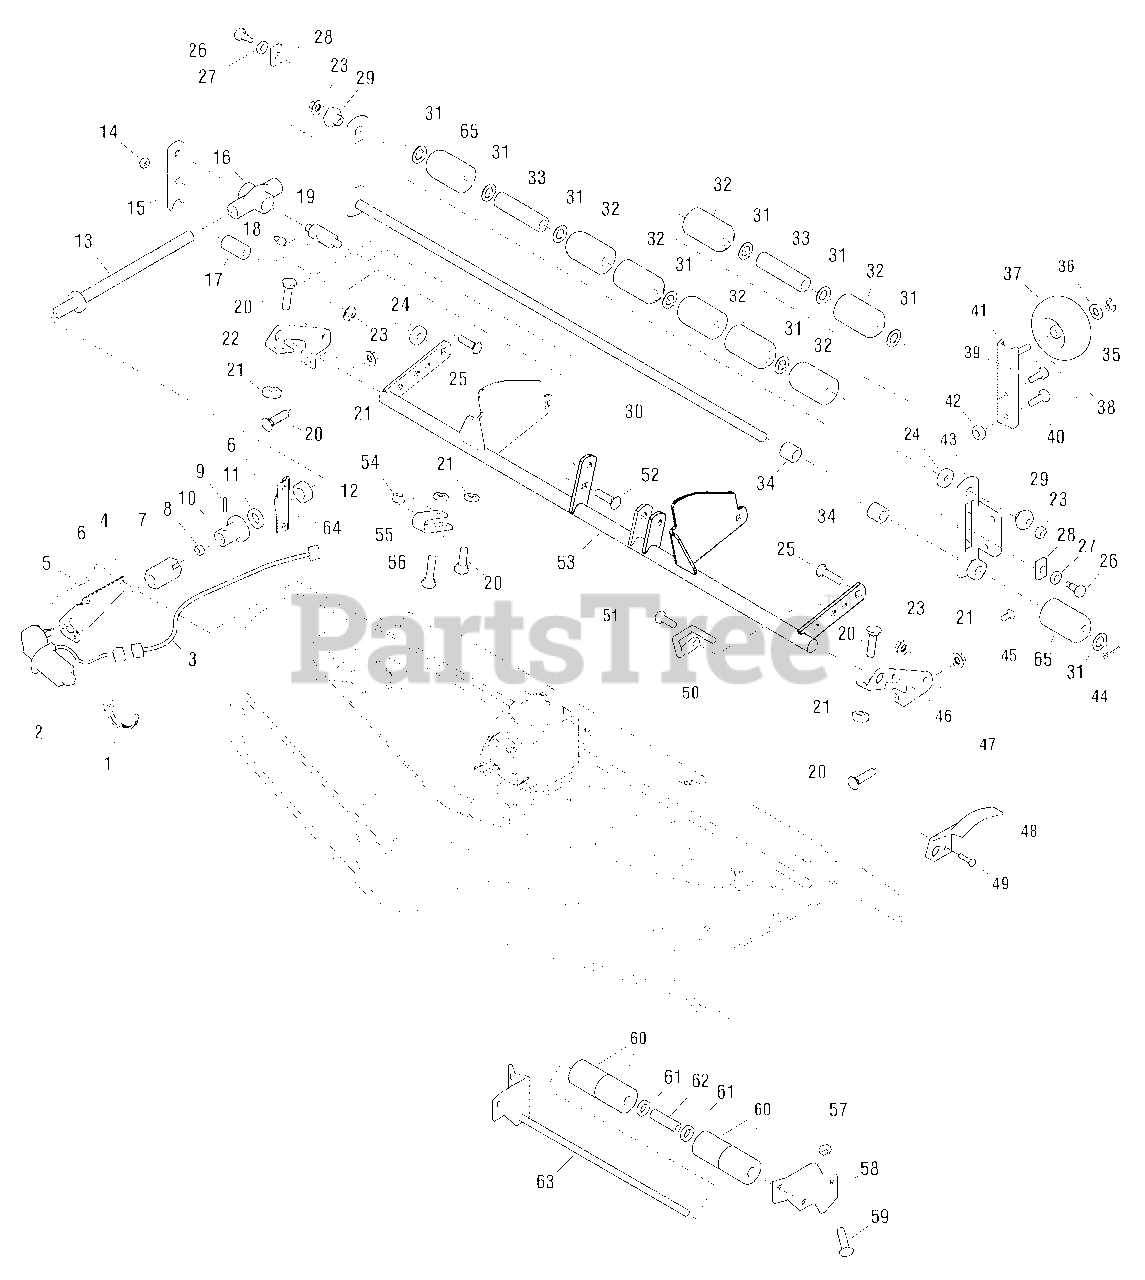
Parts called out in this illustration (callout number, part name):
1	TIE, Self Locking
2	MOTOR, Electric
3	HARNESS ASSEMBLY
4	BRACE, Height of Cut
5	CAPSCREW, Hex, SEMS Washer Head, Dog Point, 1/4-20 x 7/8
6	CAPSCREW, Hex Wsher Head, 3/8-16 x 1-1/8, Black
7	ADAPTER, Motor
8	NUT, Hex, KEPS, 1/4-20, Black
9	PIN, Spring
11	WASHER, Special
12	BEARING, Thrust
13	ROD & SPACER ASSEMBLY
14	NUT, Hex, Toplock Flange,1/2-13, Black
16	COVER, Rod, Black
18	FITTING, Grease
20	CARRIAGE BOLT, Round Head Square Neck 3/8-16 x 1
21	NUT, Hex, KEPS, 3/8-16 , Black
22	BRACKET, Roller, RH
23	NUT, Hex Toplock, 3/8-16
24	WASHER, 3/8
25	CARRIAGE BOLT, 3/8-16 x 1-3/4
26	BOLT, Shoulder, 3/8-16 X 1.34
27	WASHER, 1/2
29	NUT, Hex Adjusting, .99 DIA .687
30	SHAFT & BAR ASSEMBLY
31	WASHER, 1/2
32	ROLLER
33	SPACER
34	SPACER, Short
35	RING-E RET EXT # 50 .500DIA SHAFT
36	WASHER, 1/2, Black
38	CLIP, Hair Pin
39	PIN, Round Head, Drilled, 3/8 x 1, Black
40	CAPSCREW, Hex Head, 3/8-16 x 1, Black
41	BAR & SHAFT ASSEMBLY
42	NUT, Hex Flange Lock, 3/8-16, Black
43	BAR ASSEMBLY
44	PIN, Cotter
45	SET SCREW, Square Head, 5/16-18 x 1/2, G8
46	BRACKET, Roller, LH
47	Height of Cut Decal
48	PLATE, Height Indicator
49	CAPSCREW, Hex Washer Head, Taptite, 1/4-20 x 3/8
50	ROD, Indicator
51	CAPSCREW, Hex Head, Taptite, 5/16-18 x 1/2
52	CARRIAGE BOLT, 1/2-13 x 2-1/2, Black
53	SHAFT ASSEMBLY
54	SPACER
56	CARRIAGE BOLT, 3/8-16 x 2-1/2, Black
57	NUT, Hex, KEPS, 5/16-18, Black
58	BRACKET & WASHER ASSEMBLY
59	CARRIAGE BOLT, 5/16-18 x 3/4, Black
61	WASHER, 5/8, Black
63	SHAFT & BRACKET ASSEMBLY
64	SUPPORT, Height of Cut
